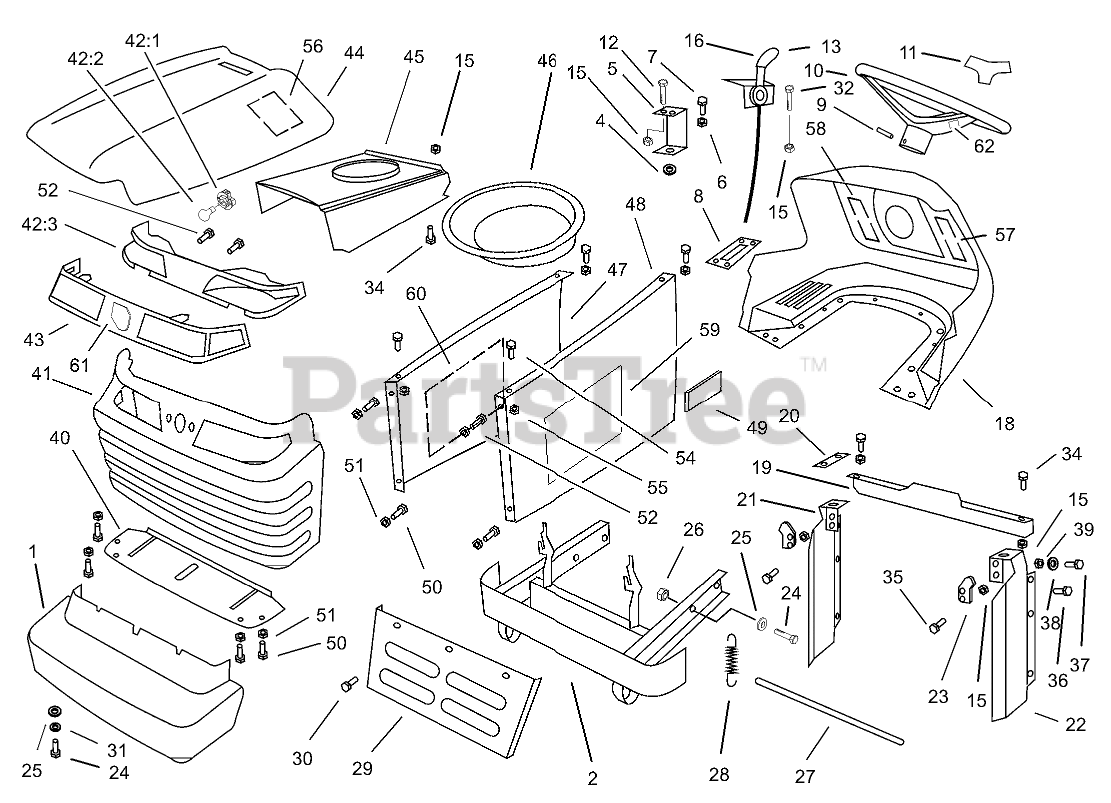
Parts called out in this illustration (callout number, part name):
1	COVER-BUMPER
2	BUMPER
4	BUSHING
5	HOLDER-TANK, FUEL
6	NUT-LOCK
9	PIN-SPIROL
10	WHEEL-STEERING 14 INCH
11	COVER-WHEEL, STEERING
12	SCREW-FLAT HEAD
15	NUT-LOCK
16	CABLE-THROTTLE and CHOKE
18	PANEL-DASH
20	BRACKET
21	PANEL-RIGHT
22	PANEL-LEFT
23	LATCH-HOOD
24	SCREW-HH
25	WASHER-PLAIN
26	NUT-LOCK, NI
27	BAR-SAFETY
28	SPRING-HOOD
29	SHIELD-HEAT
30	SCREW-TAP
31	WASHER-SPRING
38	WASHER
39	NUT-HEX
40	BRACKET
42:1	SOCKET-LIGHT
42:2	BULB
42:3	REFLECTOR-LIGHT
43	LENS - HEADLIGHT
44	HOOD-TOP
45	HOOD - BAFFLE
46	PLENNUM-AIR
47	SIDE-HOOD, LH
48	SIDE-HOOD, RH
49	FOAM-SIDEPANEL
51	NUT-HEX
52	SCREW-PLASTITE
54	SCREW-HWH
56	FOAM-HOOD
57	DECAL-PTO
58	DECAL-CHOKE/THROTTLE/KEY
59	DECAL-HOOD, LH
60	DECAL-HOOD, RH
61	EMBLEM-HORSEHEAD
62	DECAL
